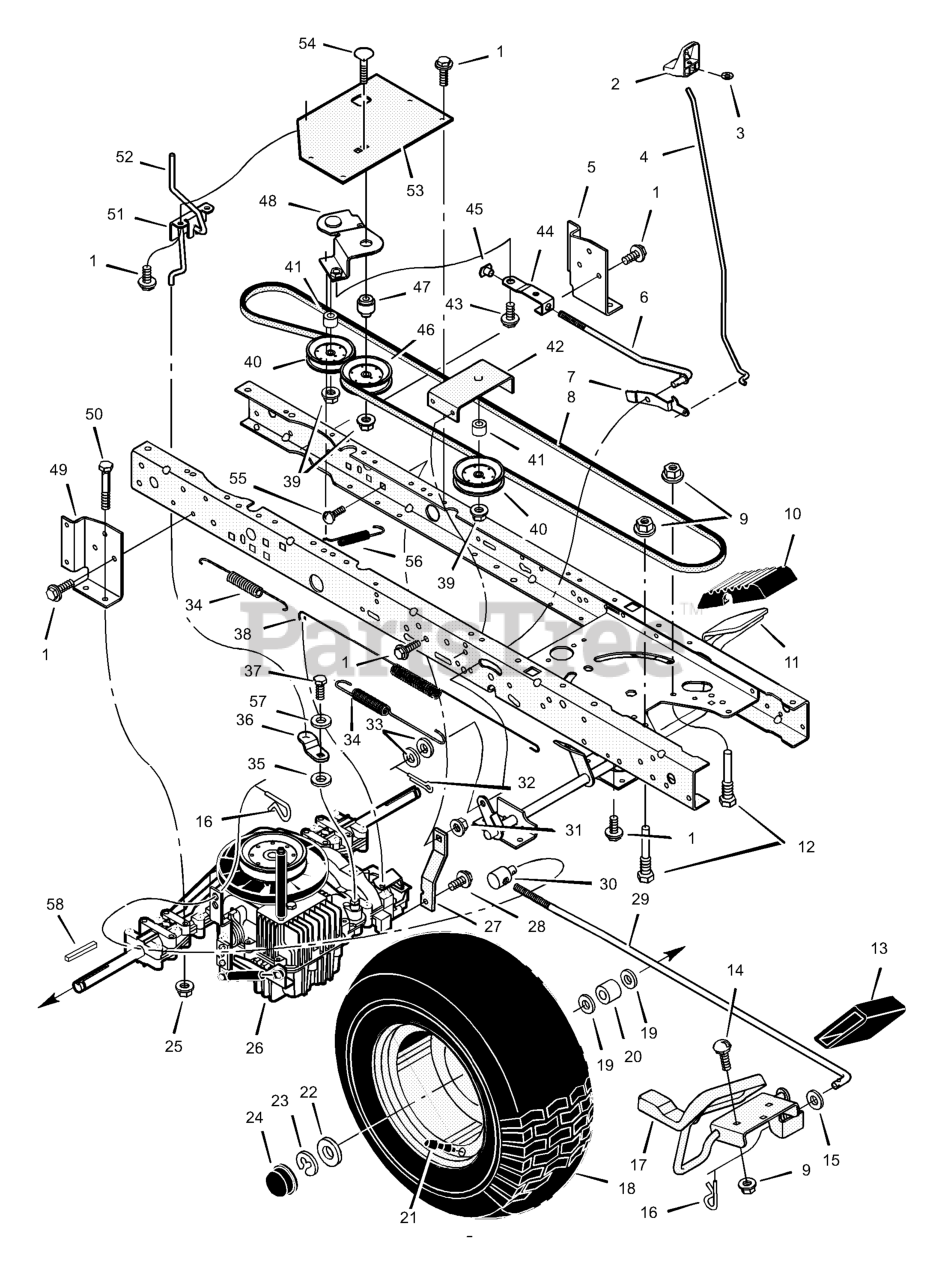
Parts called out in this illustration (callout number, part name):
2	Knob, Parking Brake
3	Nut, Push
4	Rod, Parking Brake
5	Bracket, Left Transaxle
6	Rod, Clutch
7	Latch, Parking Brake
8	V-Belt, Drive
9	Nut, Flange
10	Pad, Brake/Clutch
11	Rod Assembly, Clutch/Brake
12	Screw, Guide
13	Pad, Pedal
14	Bolt, Carriage
16	Pin, Hair
17	Pedal Assembly, Hydro
18	Wheel & Tire Assembly
20	Spacer
21	Stem, Valve
24	Cap, Hub
25	Nut, Centerlock
26	Transaxle
27	Strap, Torque
29	Rod, Control
30	NUT, Adjusting, 1/2-13
31	Nut, Centerlock
32	Pin, Cotter
34	Spring, Extension
36	ARM, Disconnect
37	Capscrew
38	Spring, Brake
39	Locknut, Flange
40	Pulley, Idler
42	Bracket, Idler Assembly
43	Bolt, Shoulder
44	Link, Clutch
45	Nut, Tee
46	Pulley, Idler
47	Bushing, Pivot
48	Arm Assembly, Idler
49	Bracket, Right Transaxle
50	Bolt, Hex
51	Bracket, Disconnect
52	Rod, Disconnect
53	Bracket, Idler Pivot
54	Bolt, Carriage
55	Bolt, Carriage
56	Spring, Clutch
58	Key, Square
